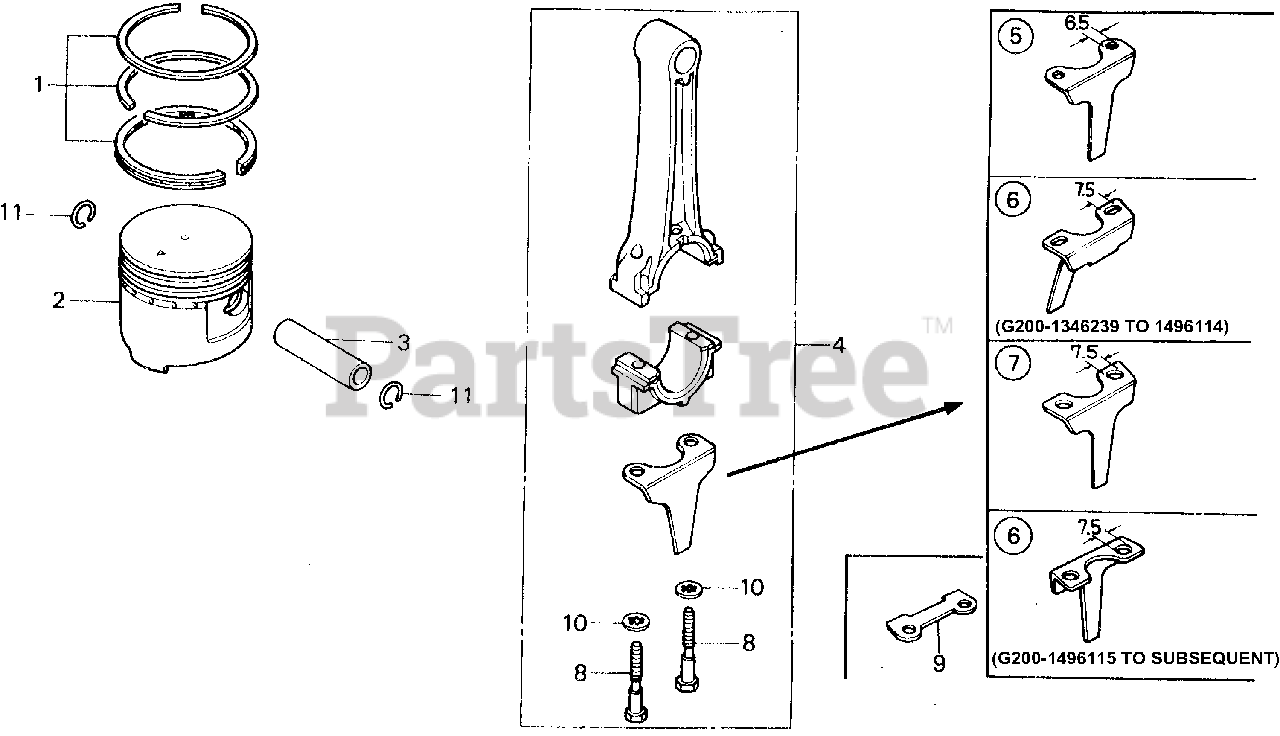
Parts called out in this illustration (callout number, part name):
1	RING SET, PISTON (STD) (NIPPON)
1	RING SET, PISTON (0.25)
1	RING SET, PISTON (0.50)
1	RING SET, PISTON (0.50) Use up to Engine SN 1152170.
1	RING SET, PISTON (0.75)
2	PISTON (STD)
2	PISTON (0.25)
2	PISTON (0.50)
2	PISTON (0.75)
3	PIN, PISTON
4	ROD ASSY., CONNECTING
4	ROD ASSY., CONNECTING Use from Engine SN 1179852 to 1269498.
5	DIPPER, CONNECTING ROD
5	DIPPER, CONNECTING ROD (NOT AVAILABLE)
6	DIPPER, CONNECTING ROD
7	DIPPER, CONNECTING ROD (NOT AVAILABLE)
8	BOLT, CONNECTING ROD (6MM)
8	BOLT, CONNECTING ROD (6MM) (NOT AVAILABLE)
8	BOLT, CONNECTING ROD (7MM)
9	WASHER B, CONNECTING ROD
10	WASHER, LOCK (6MM) (N/A: SEE ASSEMBLY)
10	WASHER, LOCK (7MM)
11	CLIP, PISTON PIN (15MM)
